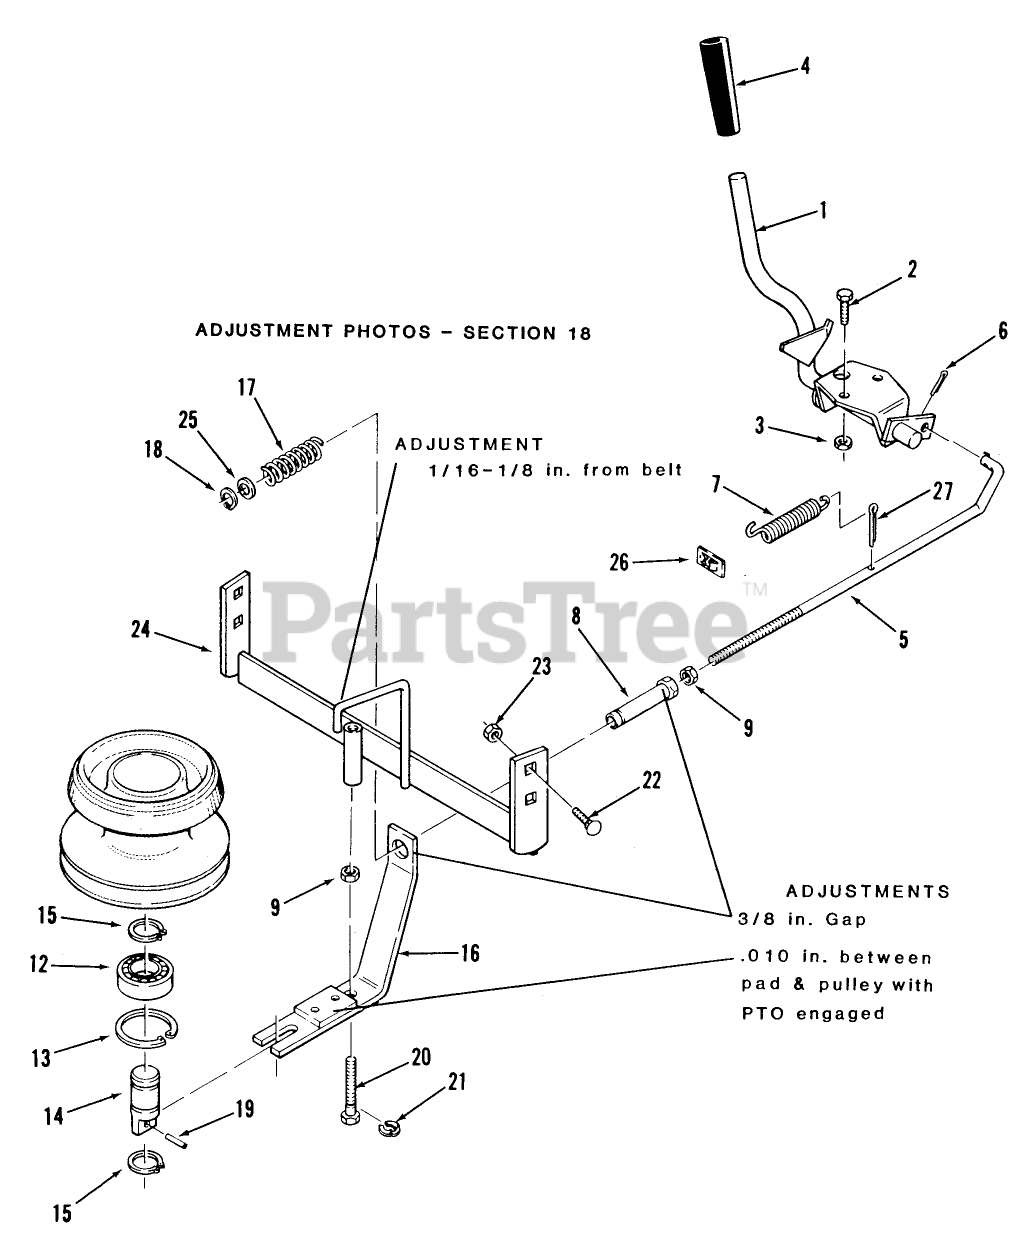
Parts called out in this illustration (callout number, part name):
1	ASSY-HANDLE
2	Bolt
3	Nut
4	GRIP
5	PTO Clutch Rod
6	Cotter Pin
7	Spring
8	TUBE-CLUTCH SPACER
9	Jam Nut 5/16-18
12	BEARING-BALL
13	Ring-Snap
14	Shaft Clutch Hsg
15	RING-SNAP, EXTERNAL
16	ASM-CLUTCH BRAKE PTO
17	SPRING-CLUTCH
17	SPRING-COMPRESSION
18	Retaining Ring
19	SPIROL PIN 7/32X7/8
20	SCREW-CLUTCH ADJUST
21	E-Ring
22	Bolt
23	Nut
24	Clutch Mounting Bracket
24	Clutch Mounting Bracket 216-5 Only
25	Washer
26	SPEED NUT
27	Pop Rivet
